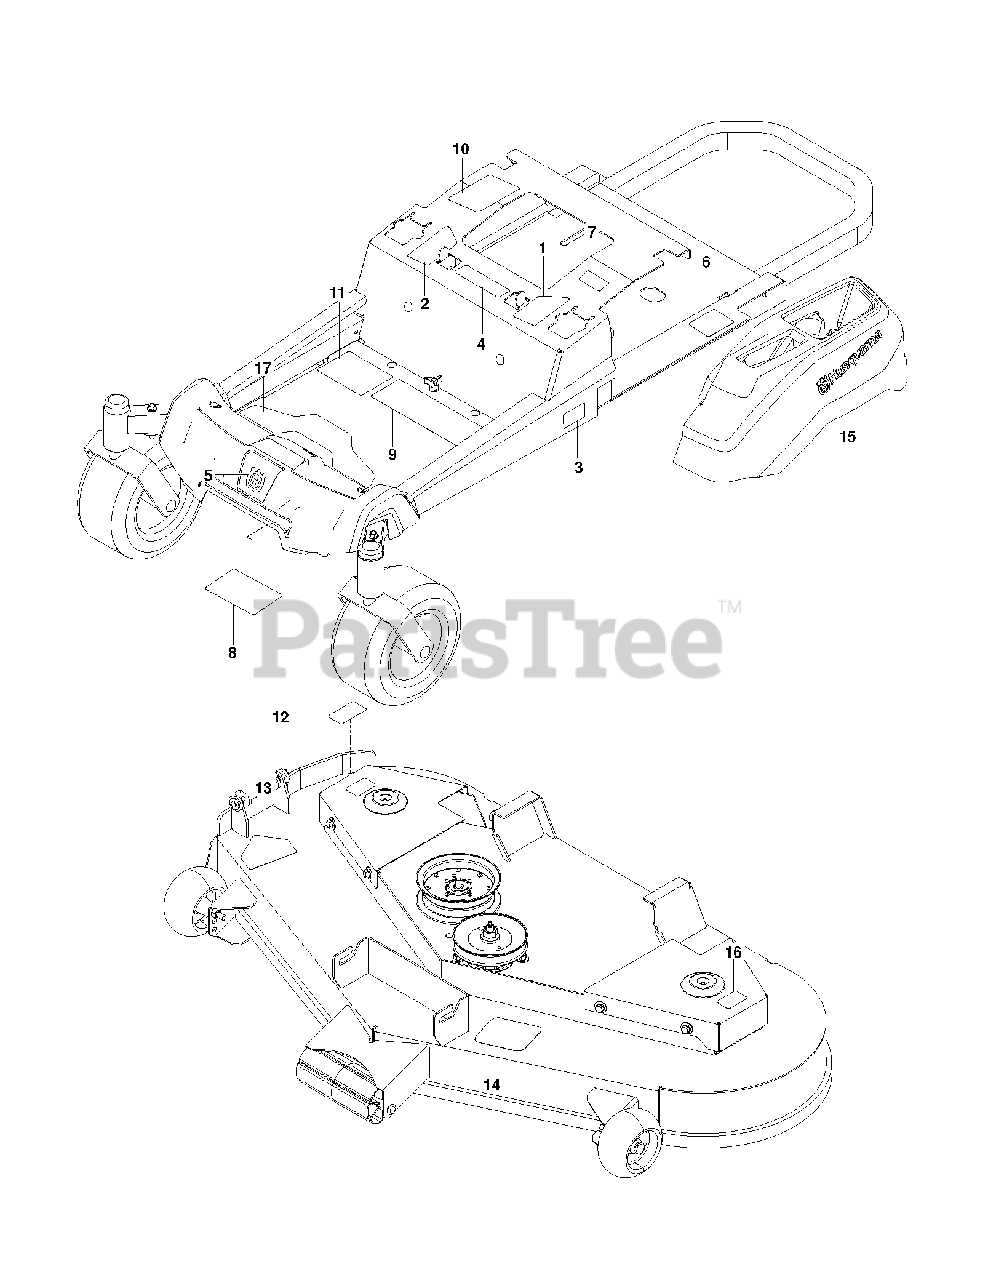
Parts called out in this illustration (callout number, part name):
1	DECAL.ZTR.RZ.THRTL/PRKBRK.V2.L
2	DECAL.ZTR.RZ.THRTL/PRKBRK.V2.R
3	DECAL.ZTR.SIDERAIL.MN.Z248F.HU
4	EURO DECAL-BATTERY WARNIN6
5	DECAL.BADGE.55MM.CROWNH.HUSQ
6	DECAL, DO NOT TOW
7	DECAL, EXITING MOWER
8	DECAL, SERVICE
9	DECAL, SAFETY WARNING
10	DECAL, CUSTOMER RESPNSIBILITY
11	DECAL.ZTR.STRTNGINST.REMOTECHK
12	DECAL.DECK.6MIL./DEF.SHLD.WARN
13	DECAL, DECK DEFLECTOR, WARNING
14	DECAL, BELT ROUTING
15	DECAL.HUSQVARNA.210MM
16	DECAL.DECK.6MIL.EURO.NOSTEP
17	PAD.RZ.FOOTREST.PLATE
